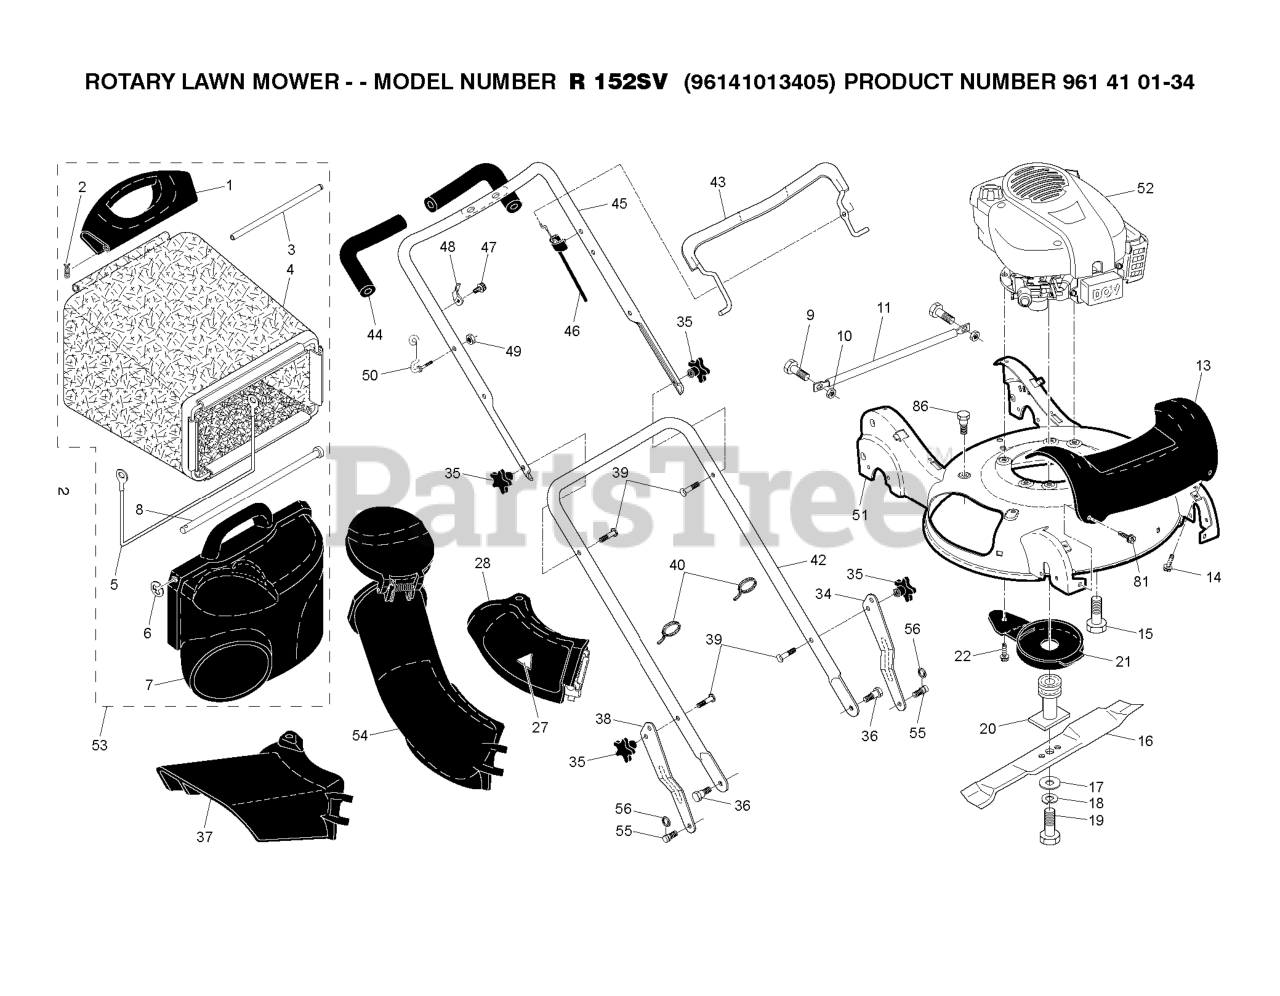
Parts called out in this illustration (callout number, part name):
1	HANDLE.GRASSBAG.REAR.H-GRAY
2	COTTER PIN (3 2)(2 2MC)
3	ROD.REAR.HANDLE.YELLOW
5	FRAME, GRASSBAG
7	DOOR, GRASSBAG
8	ROD, PIVOT
10	LOCKNUT.NYLOC.1/4-20
11	TUBE, REAR SKIRT
13	COVER.FRONT.21.HV.H-GRAY
14	SCREW, HEX WASHER HEAD
15	BOLT 3/8-16X1-1/8
16	Blade, 21"
17	WASHER,HARDEN
18	LOCKWASHER
19	BOLT.HD.HEAD.3/8-24X2.50 (2 2)
20	ADAPTER.BLADE
21	DEBRIS SHEILD
22	SCREW 1/4X20
27	DECAL.INTERNATIONL.CUTFINGER
34	ADJUSTMENT BRACKET, LOWER LH
35	KNOB.HANDLE.PLASTIC.STAR.BLACK
36	SCREW.5/16X.680.TRIM.H
38	BRACKET.ADJ.LOWER.HDL.RT.GREY
39	BOLT, HANDLE 5/16-18X1.75
40	TIE GUIDE
42	HANDLE.LOWER.GREY
43	BAIL.CONTROL.MZR.BS.ORANGE
44	GRIP.HANDLE.FOAM.WIDE.(1 SIDE)
45	HANDLE.ASM.UPPER.W/GRIP
46	CABLE.MZR.SNAP-IN
48	BRACKET.UPSTOP.RT
49	NUT
50	GUIDE.ROPE.WALK.MOWER
53	Grassbag Assembly, Complete
55	STUD.SHOULDER.T45.BZP
56	E-RING 7/16 RE
81	SCREW.HWH.13-16-5.8.BZP
